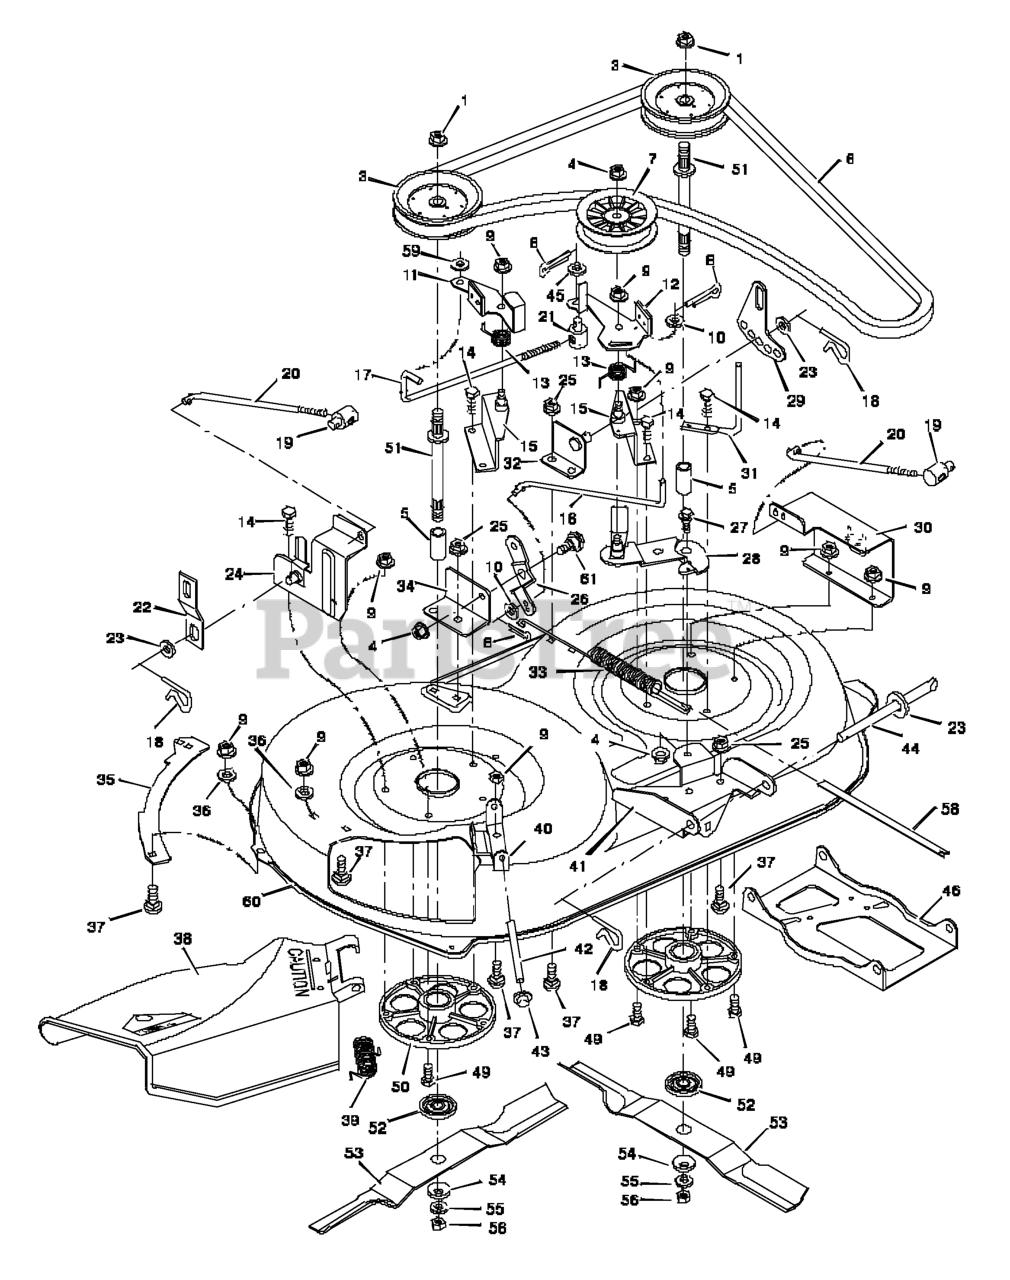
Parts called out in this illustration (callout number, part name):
1	Nut, Hex
3	Pulley, Jackshaft
4	Locknut, Flange
5	Spacer
6	Belt, Blade Drive
7	Pulley, Idler
8	Pin, Cotter
9	Locknut, Flange
10	Washer
11	Brake Assembly, Right
12	Brake Assembly, Left
13	Spring, Torsion
14	Bolt, Hex
15	Bracket Assembly, Brake
16	Rod, Brake
17	Rod, Cross Link
18	Pin, Hair
19	Nut, Adjustable
20	Rod, Adjuster
21	Nut, Adjustable
22	Link, Suspension
24	Bracket Assembly, Right Lifter
25	Nut, Flange
26	Bracket, Pivot
27	Bolt, Shoulder
28	Arm Assembly, Idler
29	Plate, Adjuster
30	Cover, Pulley
31	Guide, Belt
32	Bracket Assembly, Left Lifter
33	Spring, Extension
34	Bracket, Pivot
35	Plate
37	Bolt, Carriage
38	Deflector Assembly, Chute
39	Spring, Torsion
40	Bracket, Hinge
41	Bracket, Front Hanger
42	Rod, Deflector
43	Cap, Push On
44	Rod, Hanger
46	Hanger, Front
49	CAPSCREW, Hex Head, 5/16-18 x 1
50	Housing, Jackshaft
51	Jackshaft
52	Adapter, Blade
53	Blade, 40" (2 required)
54	Washer, Belleville
56	Nut, Hex
58	Indicator, Plastic
60	Housing, Blade (40")
61	Bolt, Shoulder
